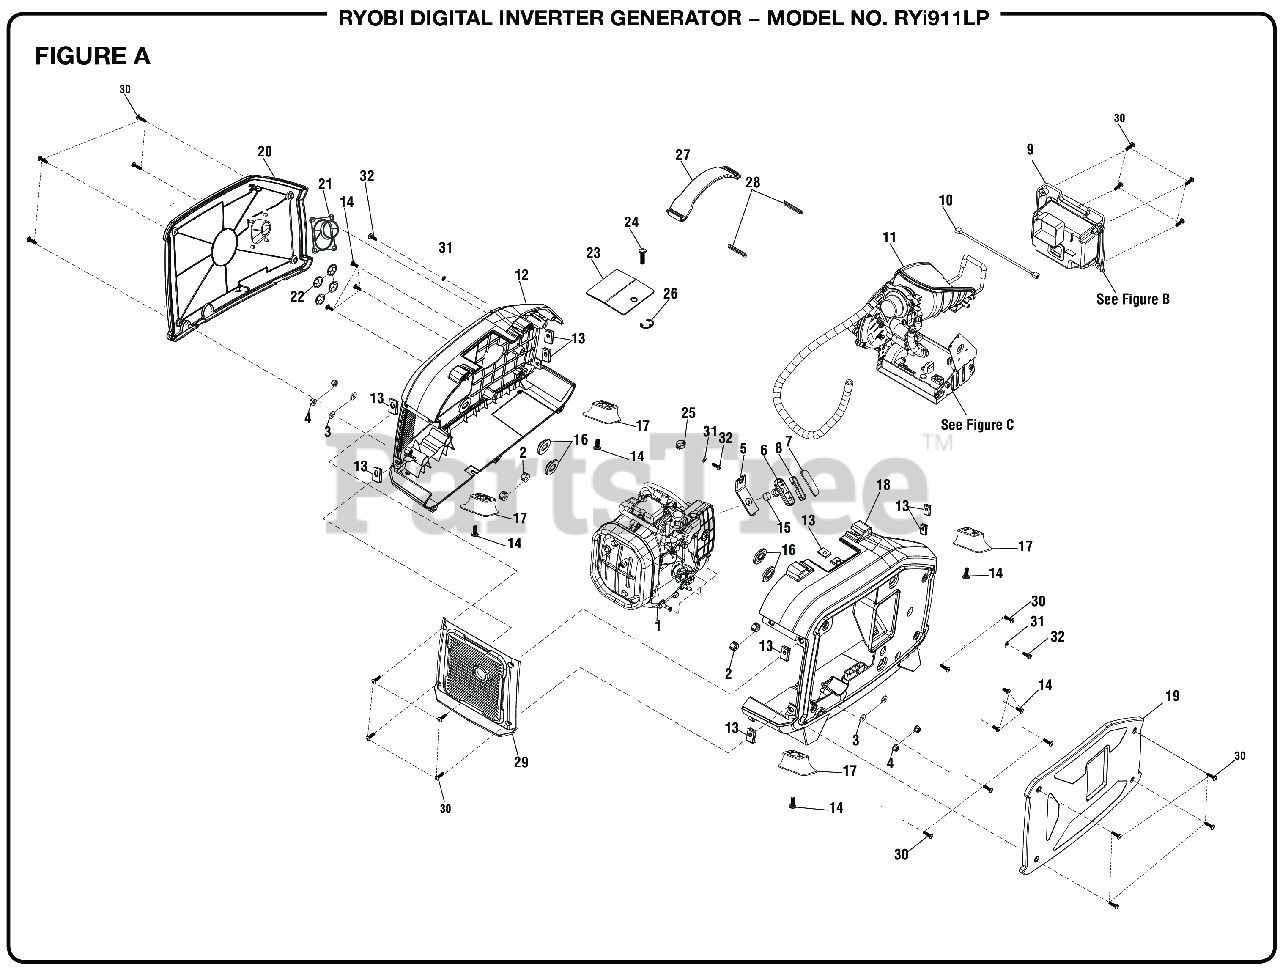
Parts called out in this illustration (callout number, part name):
1	Engine
2	Side Engine Isolator
3	Rubber Washer (ID6.25 x OD15.5 x 2t)
4	Lock Flange Nut (M6)
5	Starter Cover
6	Recoil Handle
7	Recoil Handle Cover
8	Recoil Handle Support
9	Control Panel Assembly
10	Stepper Motor Extended Wire Harness
11	Fuel System & Bracket Assembly
12	Panel Housing (Right)
14	Screw (M5 x 12 mm, T-25 Torx Washer Pan Hd.)
15	Rubber Grommet Handle
16	Rubber Grommet
17	Rubber Foot w/Metal Insert and Ribs
18	Panel Housing (Left)
19	Maintenance Panel (Left)
20	Maintenance Panel (Right)
21	Rubber Grommet
22	Internal Tooth Washer (ID5)
23	Spark Plug Door
24	Screw (M5 x 16 mm, T-25 Torx Washer Pan Hd.)
25	Fuel Hose Clamp
26	E-Clip Lock Washer
27	Rubber Handle (Upper)
28	Side Lock (U-Shaped)
29	Muffler Cover
30	Screw (M5 x 18 mm, T-25 Torx Washer Pan Hd.)
31	Washer (ID5.2 x OD10 x 1t)
32	Screw (M5 x 16 mm, T-25 Torx Pan Hd.)
